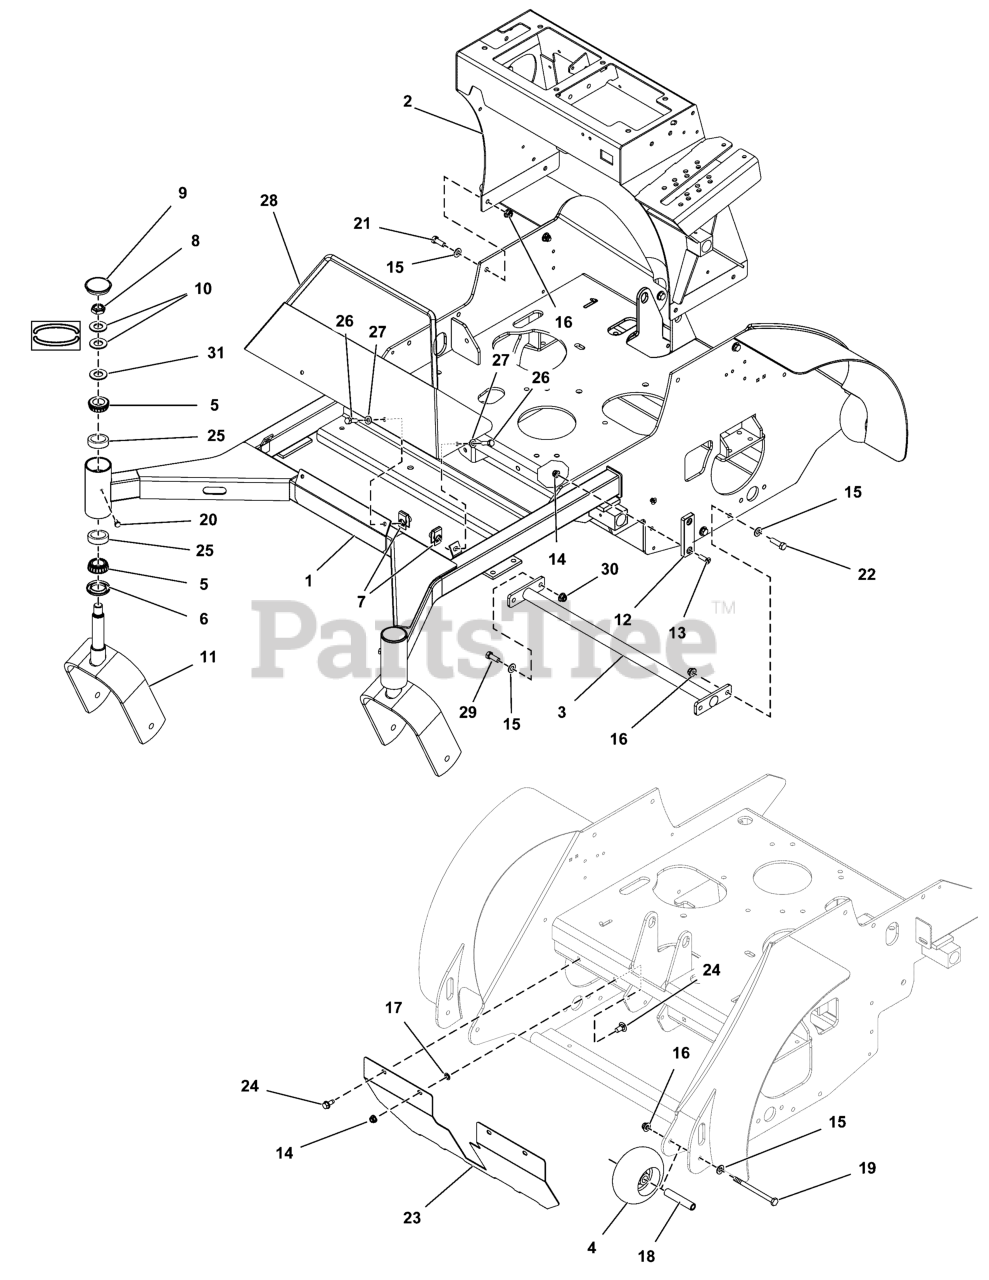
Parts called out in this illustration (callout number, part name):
1	FRAME
2	WELD, CONTROL TOWER, SRS Z2 - RED
3	WELD, CENTER CROSS BRACE - BLK
4	WHEEL, ANTI SCALP, 5"
5	BEARING, TAPERED ROLLER, 1"
6	SEAL, GREASE
7	BODY CLIP, 5/16-18-7GA MATERIAL
8	NUT, 3/4-16, HEX JAM NYLON LOCK
9	CAP, GREASE, LOW PROFILE
10	WASHER, BELLEVILLE - 1.500 X .755
11	WELD, CASTER YOKE - RED
12	PAD, FRICTION, .375 X 1.25 X 4.00
13	SCREW, 5/16-18 X 1, PHILLIPS HD, BZ
14	NUT, 5/16-18 HEX NYLOCK FLANGE NUT
15	WASHER, 3/8 SAE
16	NUT, 3/8 - 16 HEX NYLOCK FLANGE
17	5/16" PUSH-ON NUT RETAINER, STL, CZ
18	SPACER, .38 X .63 X 3.38, CZ
19	BOLT, 3/8-16 X 4-1/2" GD5 CZ
20	BOLT, 1/4-28 X 1/2, GD5 YZ
21	BOLT, 3/8-16 X 1" GD5 CZ
22	BOLT, 3/8-16 X 1-1/4" GD5 CZ
23	PLATE, HEAT SHIELD, STAND ON - RED
24	BOLT, 5/16-18 X 3/4, CARRIAGE, GD5, CZ
25	CUP, BEARING (SV)
26	BOLT, 5/16-18 X 1" GRD5 YZ
27	WASHER, 5/16" SAE
28	WELD, FRONT GUARD, SRS Z2 61 - RED
29	BOLT, 3/8-16 X 1-1/2" GD5 CZ
30	NUT, Hex, Side Lock, 3/8-16
31	WASHER, 3/4 SAE
